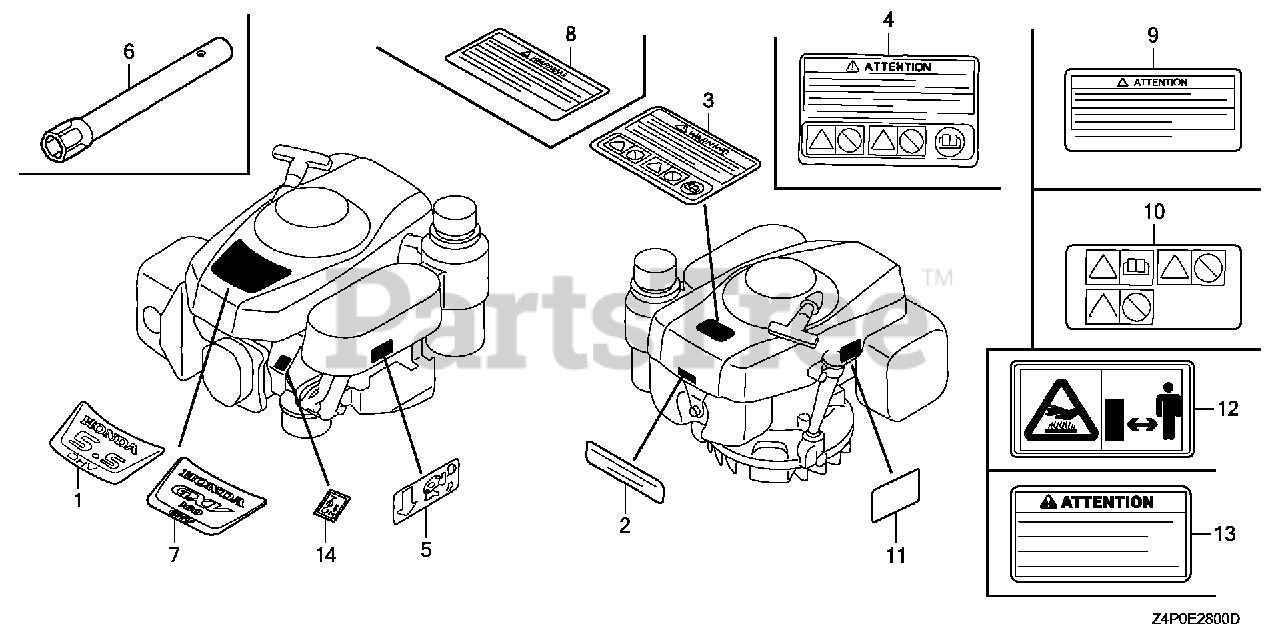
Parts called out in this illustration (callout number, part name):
1	MARK, EMBLEM (GXV160)
2	MARK, MANUFACTURER
3	MARK, OPERATOR CAUTION (ENGLISH)
3	MARK, OPERATOR CAUTION (PICTOGRAPH)
4	MARK, OPERATOR CAUTION (FRENCH)
5	MARK, FUEL PETCOCK CAUTION
6	WRENCH, BOX (P21)
7	MARK, EMBLEM (GXV160)
8	MARK, OPERATOR CAUTION (ENGLISH)
9	MARK, OPERATOR CAUTION (FRENCH)
10	MARK, OPERATOR CAUTION (PICTOGRAPH)
11	MARK, EX. CAUTION (ENGLISH)
11	MARK, EX. CAUTION (FRENCH)
